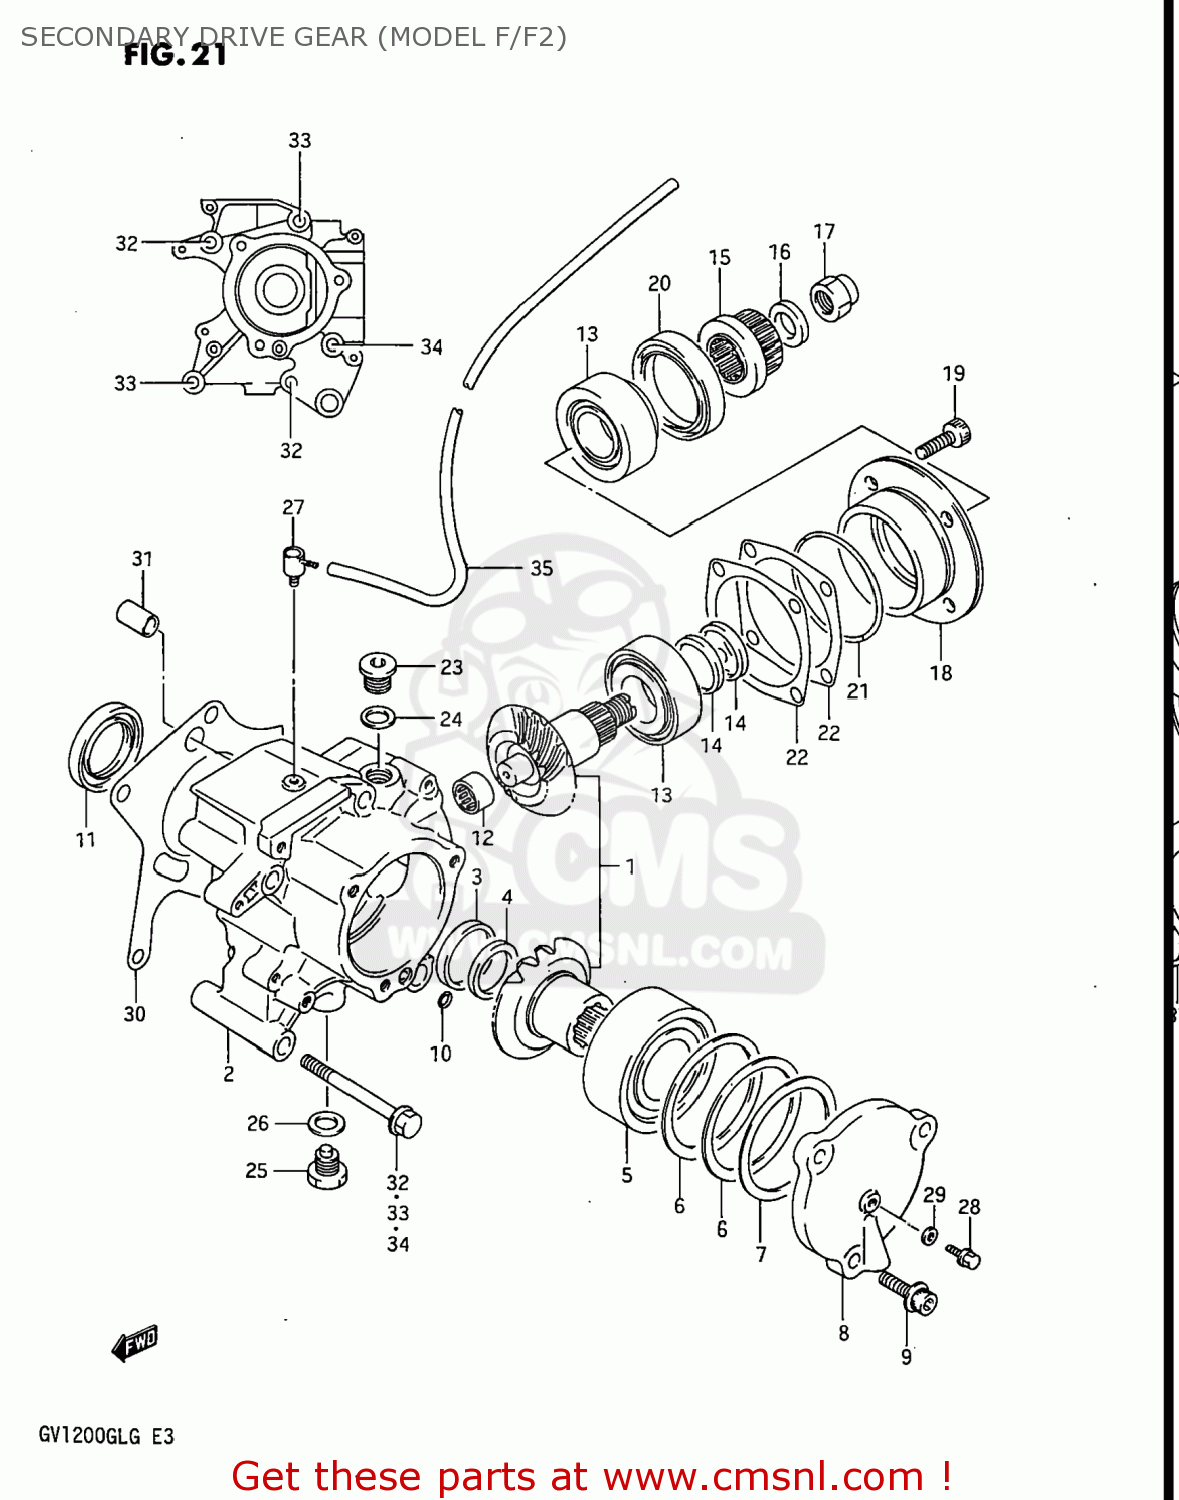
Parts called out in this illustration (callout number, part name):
1	CASE ASSY
2	CASE,SECONDARY GEAR
3	HOUSING,SECONDARY DRIVE SHIM
4	SHIM,SECONDARY DRIVE
5	BALL BEARING 35X72X27
6	SHIM,SECONDARY DRIVE
7	O-RING (D:1.9 ID:69)
8	HOUSING,SECONDARY DRIVE BEARING
9	BOLT
10	O RING(D:1.9,ID:5.7)
11	SEAL,OIL(35X52X6)
12	BEARING(16X24X12)
13	TAPER,ROLLER BEARING
14	SHIM
15	COUPLING,SECONDARY DRIVE
16	WASHER(16X29X4)
17	NUT
18	HOUSING,SECONDARY DRIVEN BEVEL
19	BOLT
20	SEAL,OIL(48X64X6)
21	O RING(D:2.1,ID:66.2)
22	SHIM,SECONDARY DRIVEN HOUSING
23	PLUG
24	GASKET(14X19.2X2) (NAS)
25	PLUG
26	GASKET(14X19.2X2) (NAS)
27	BPLUG,BEVEL GEAR BREATHER
28	BOLT
29	GASKET(5.3X9.3X1.2) (NAS)
30	GASKET,SECONDARY GEAR CASE (MCA)
31	PIN(10.4X13X22)
32	BOLT, FRONT
33	BOLT 8X85
34	BOLT (8X95)
35	HOSE
